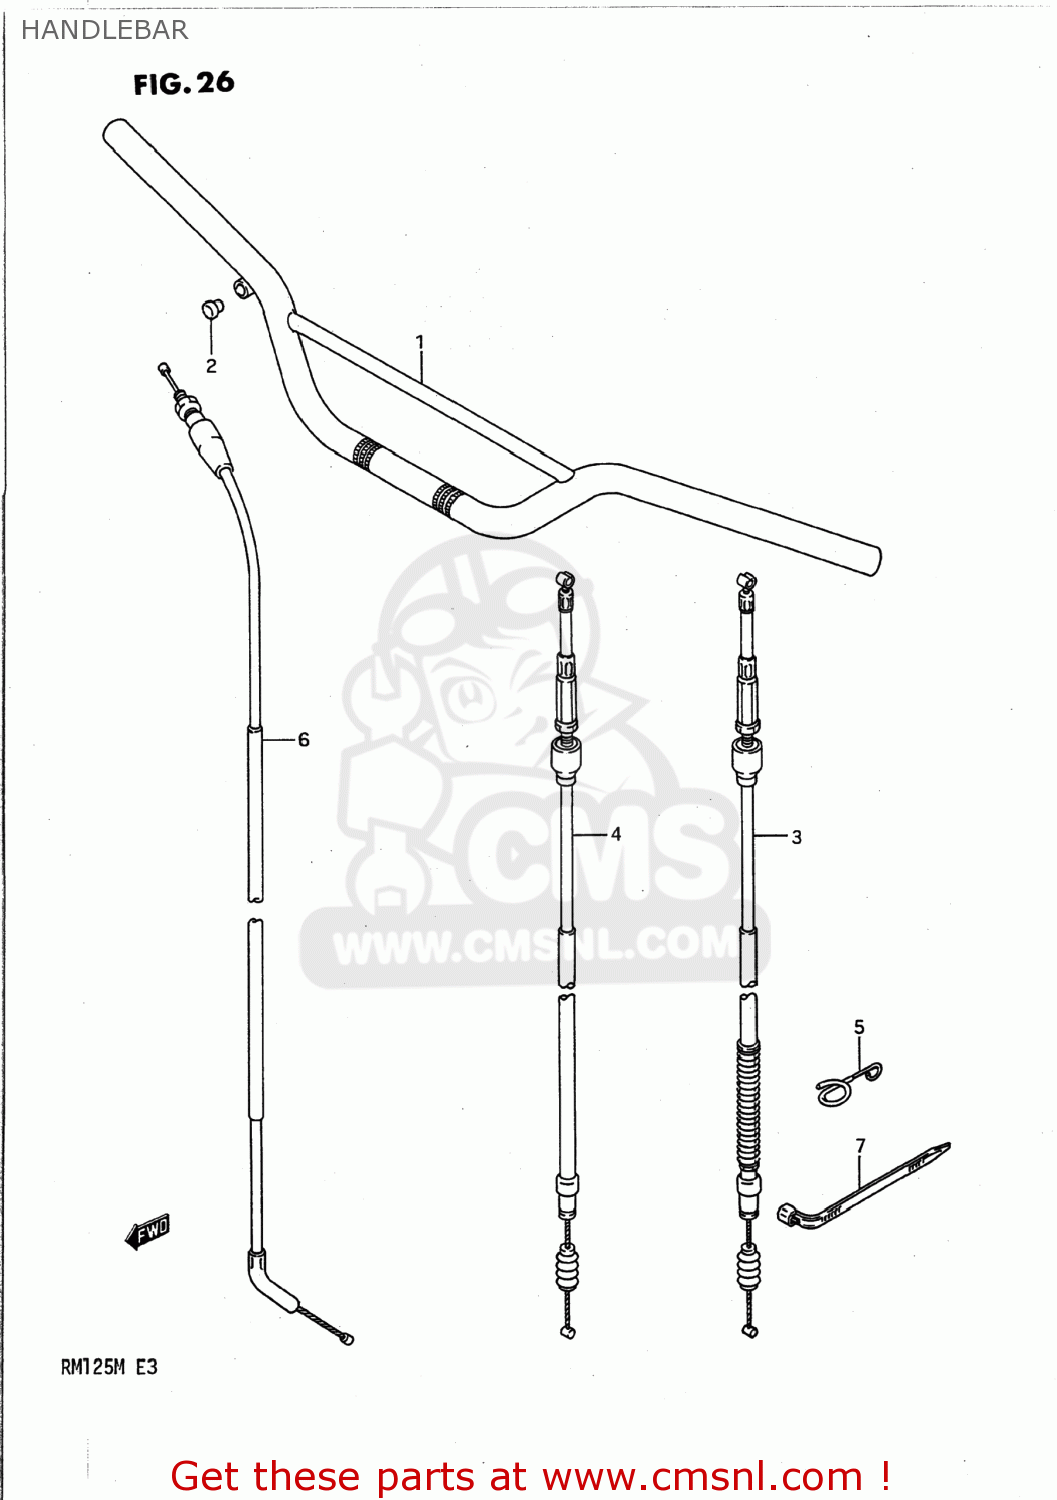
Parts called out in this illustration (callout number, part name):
1	HANDLEBAR
2	CAP(OD:14)
3	CABLE ASSY,CLUTCH
4	CABLE ASSEMBLY,CLUTCH
5	GUIDE,CLUTCH CABLE
6	CABLE ASSY,THROTTLE
7	CLAMP(L:125)
